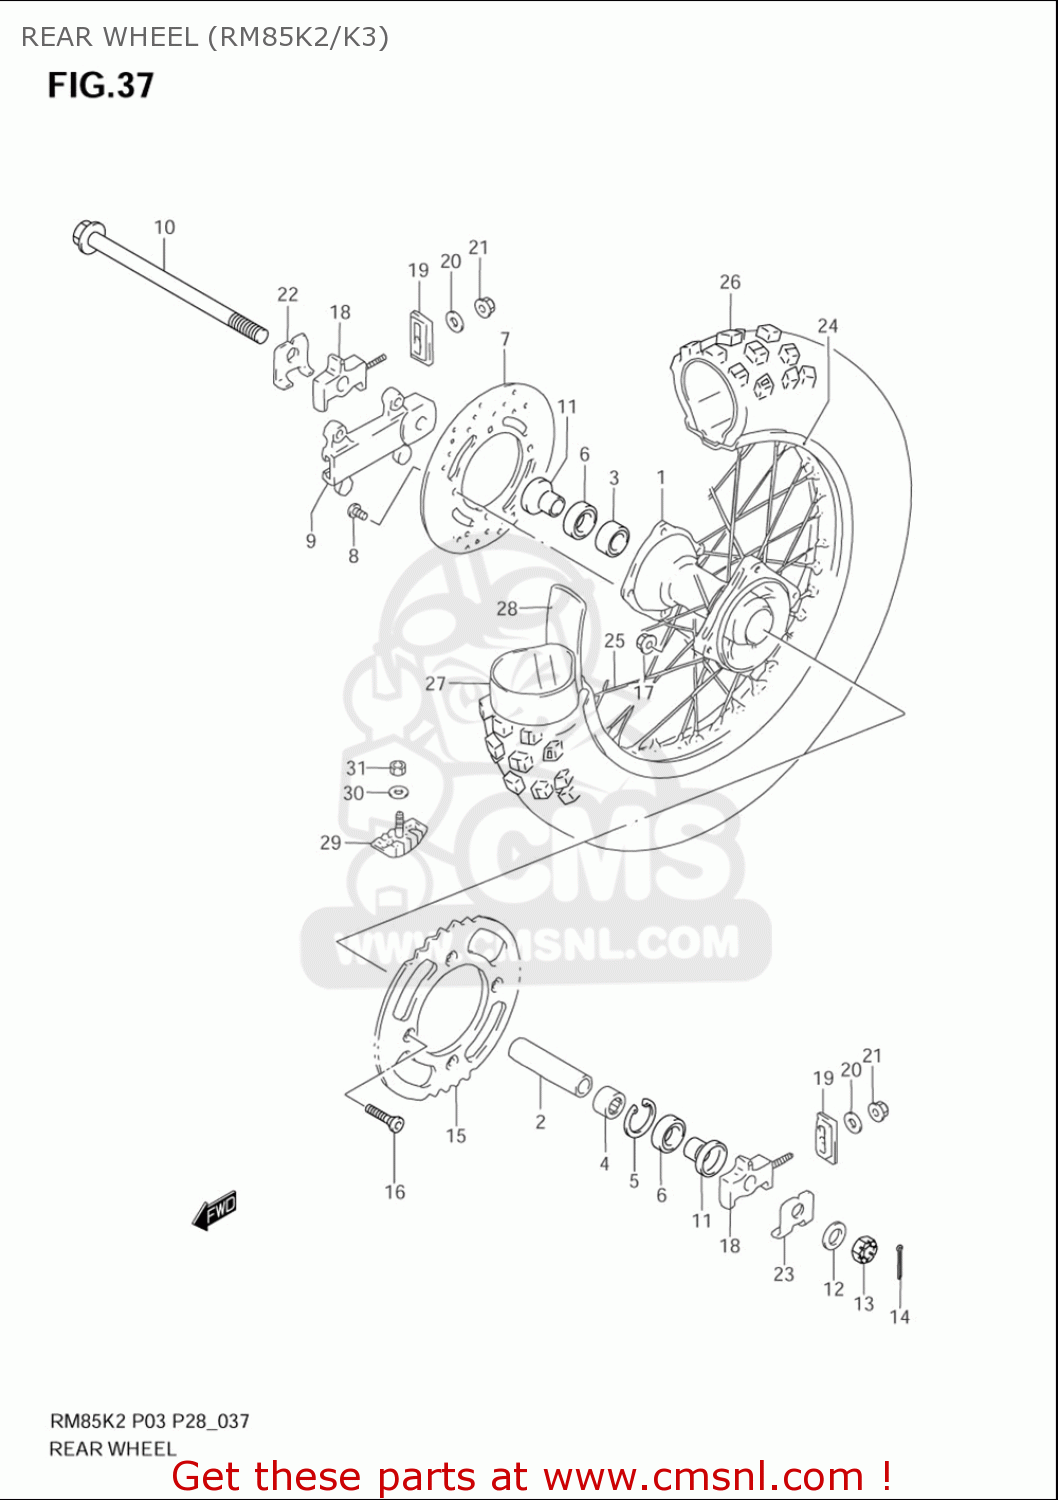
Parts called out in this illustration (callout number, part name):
1	HUB,RR WHEEL
2	SPACER,RR HUB BEARING
3	BEARING
4	BEARING(15X35X11)
5	CIRCLIP
6	SEAL,OIL(20X35X7)
7	DISC,RR BRAKE
8	SCREW
9	BRACKET,RR AXLE
10	AXLE,RR
11	SPACER,RR AXLE
12	WASHER
13	NUT
14	PIN
15	SPROCKET,RR(47T)
16	BOLT(8X30.5)
17	NUT
18	ADJUSTER,CHAIN
19	PLATE,CHAIN ADJUSTER
20	WASHER
21	NUT 6MM
22	WASHER,CHAIN ADJUSTER RH
23	WASHER,CHAIN ADJUSTER,L
24	RIM,RR WHEEL(1.60X14 AL)
25	SPOKE ASSY,RR WHEEL
26	TIRE,RR(90/100 14)
27	TUBE ASSY,WHEEL INNER
28	PROTECTOR,WHL INR TUBE
29	STOPPER,BEAD(1.85)
30	WASHER
31	NUT
